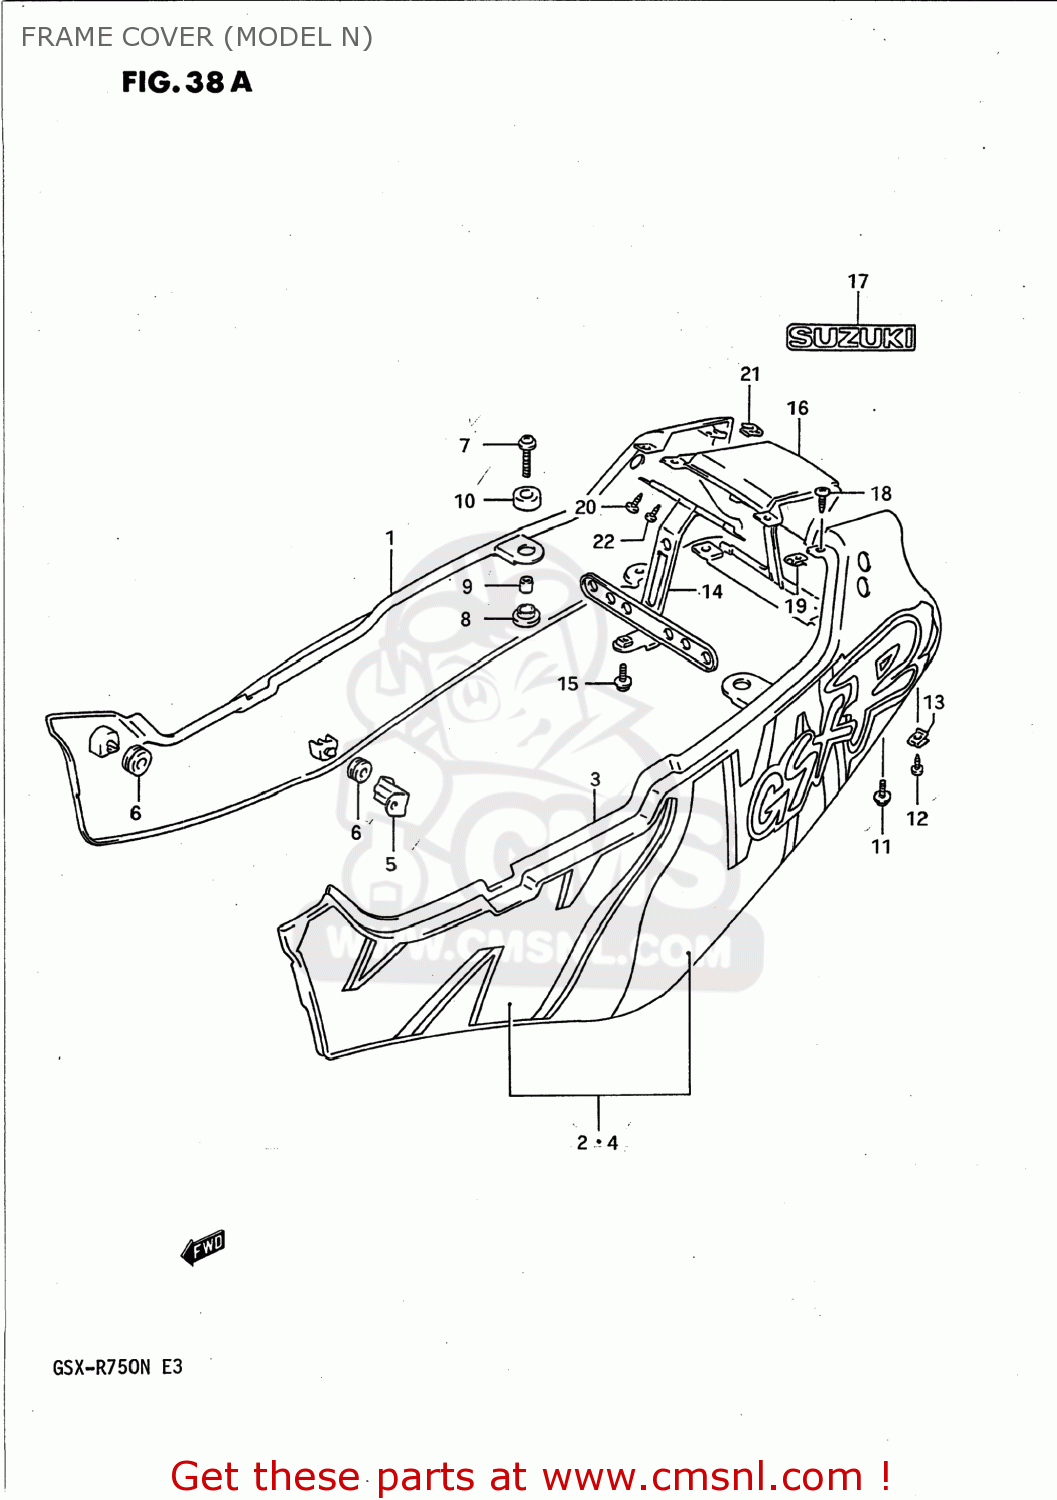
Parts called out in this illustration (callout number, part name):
1	COVER COMP,FRAME,RIGHT
2	TAPE SET,FRAME COVER,R
3	COVER,FRAME,L(BLACK)
4	TAPE SET,FRAME COVER,L
5	BRACKET,FRAME COVER
6	CUSHION
7	SCREW (6X16)
8	CUSHION,FRAME COVER LWR
9	SPACER
10	CUSHION,TAIL COVER UPR
11	SCREW(6X30)
12	SCREW
13	NUT
14	BRACKET,TAIL LAMP
15	BOLT
16	COVER,FRAME CTR
17	EMBLEM
18	SCREW, BRACKET
19	NUT
20	SCREW, BRACKET
21	NUT
22	SCREW
